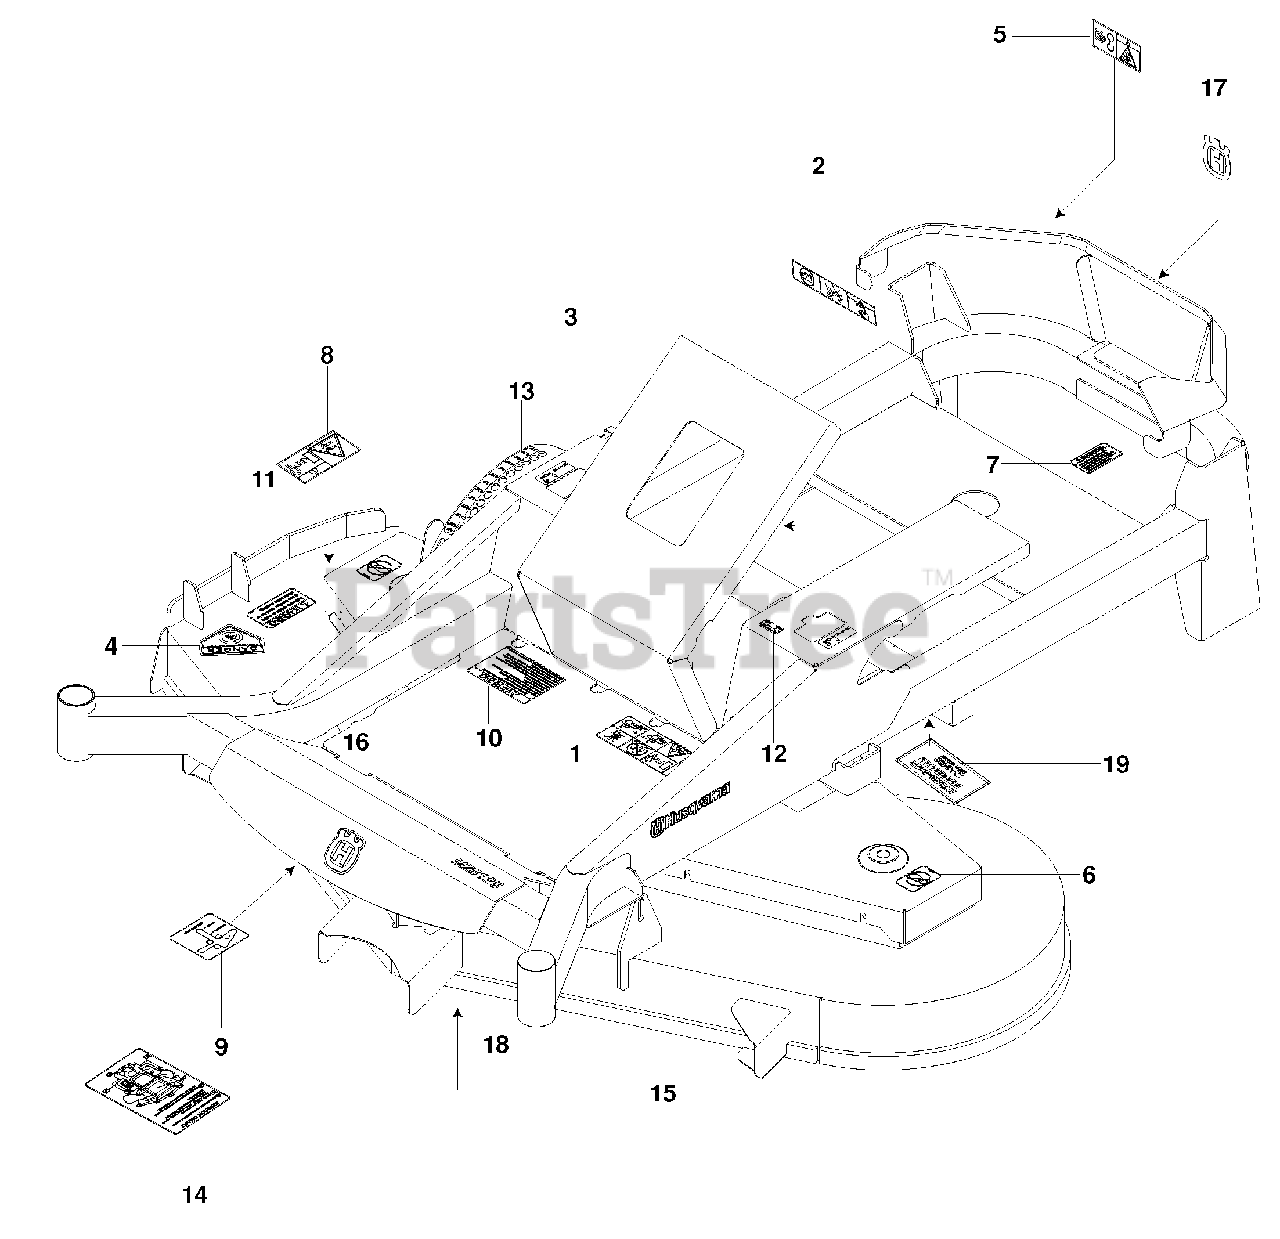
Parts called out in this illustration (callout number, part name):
1	DECAL, WARNING
2	DECAL, BATTERY WARNING
3	DECAL, MOTION CONTROL
4	DECAL, CPSC
5	DECAL, DANGER BLT DRIVE
6	DECAL, NO STEP
7	DECAL, PROP 65
8	DECAL, SEVERING
9	DECAL, BELT ROUTING
10	DECAL, WARNING
11	DECAL, WARNING
12	DECAL, F.S.T
13	DECAL, HEIGHT ADJUST
14	DECAL, SERVICE
15	DECAL, HUSQVARNA
16	DECAL, CROWN H
17	DECAL, CROWN H
18	DECAL, M6128
19	DECAL, HYDROGEAR
